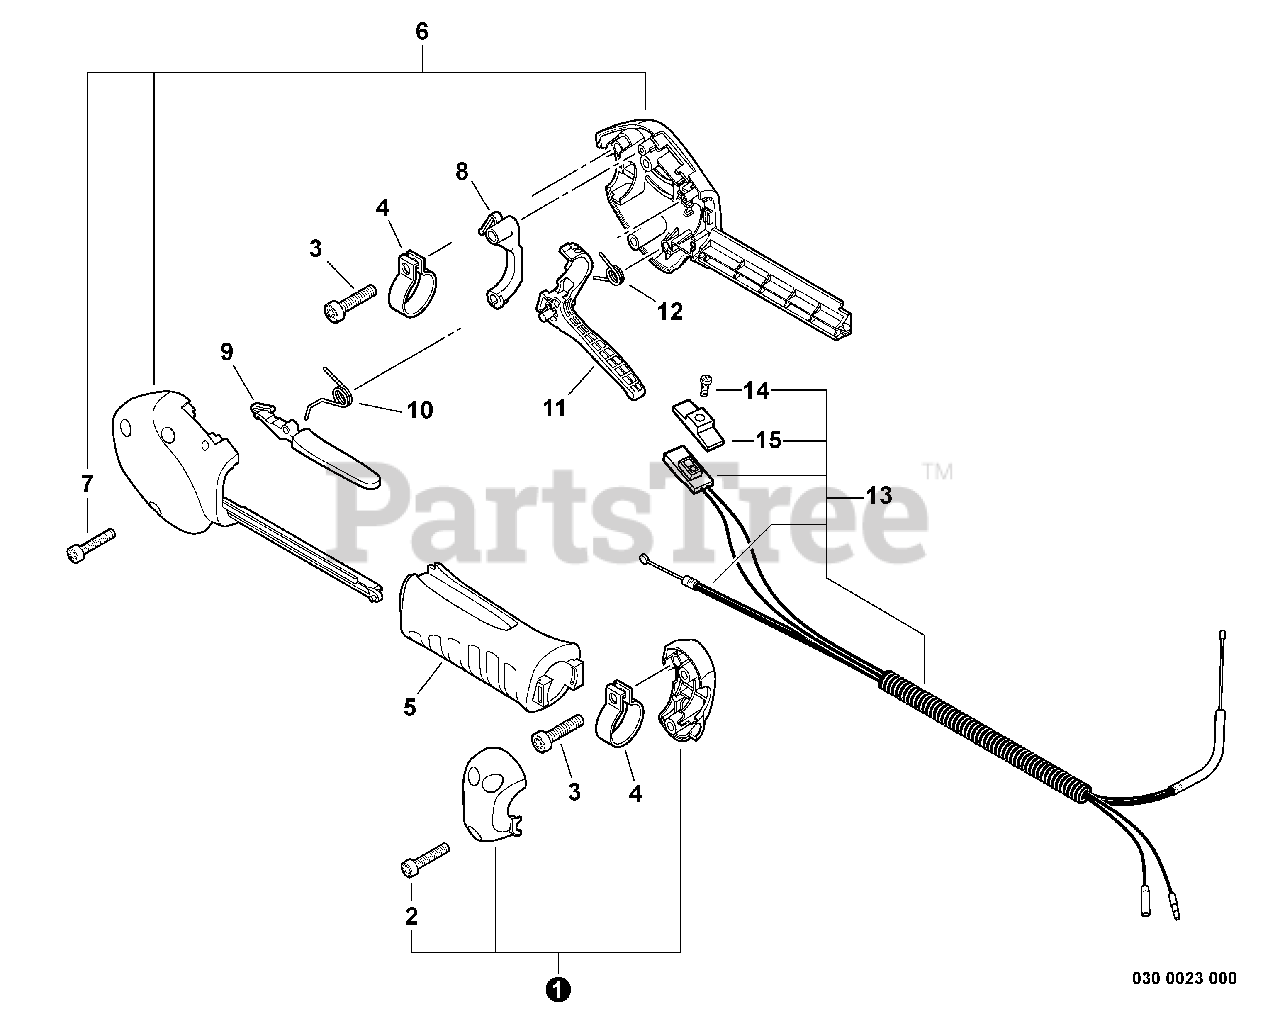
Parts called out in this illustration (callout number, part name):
1	HANDLE RETAINER KIT
2	SCREW - 5X20
3	SCREW - 5X20
5	GRIP, HANDLE
6	CONTROL HANDLE KIT
7	SCREW - 5X20
8	LOCKOUT, THROTTLE
9	LEVER, TRIGGER LOCKOUT
10	SPRING, LOCKOUT LEVER
11	TRIGGER, THROTTLE
12	SPRING, TRIGGER
13	CONTROL CABLE ASSY
14	SCREW - 3X10
15	KNOB, SWITCH - ORANGE
